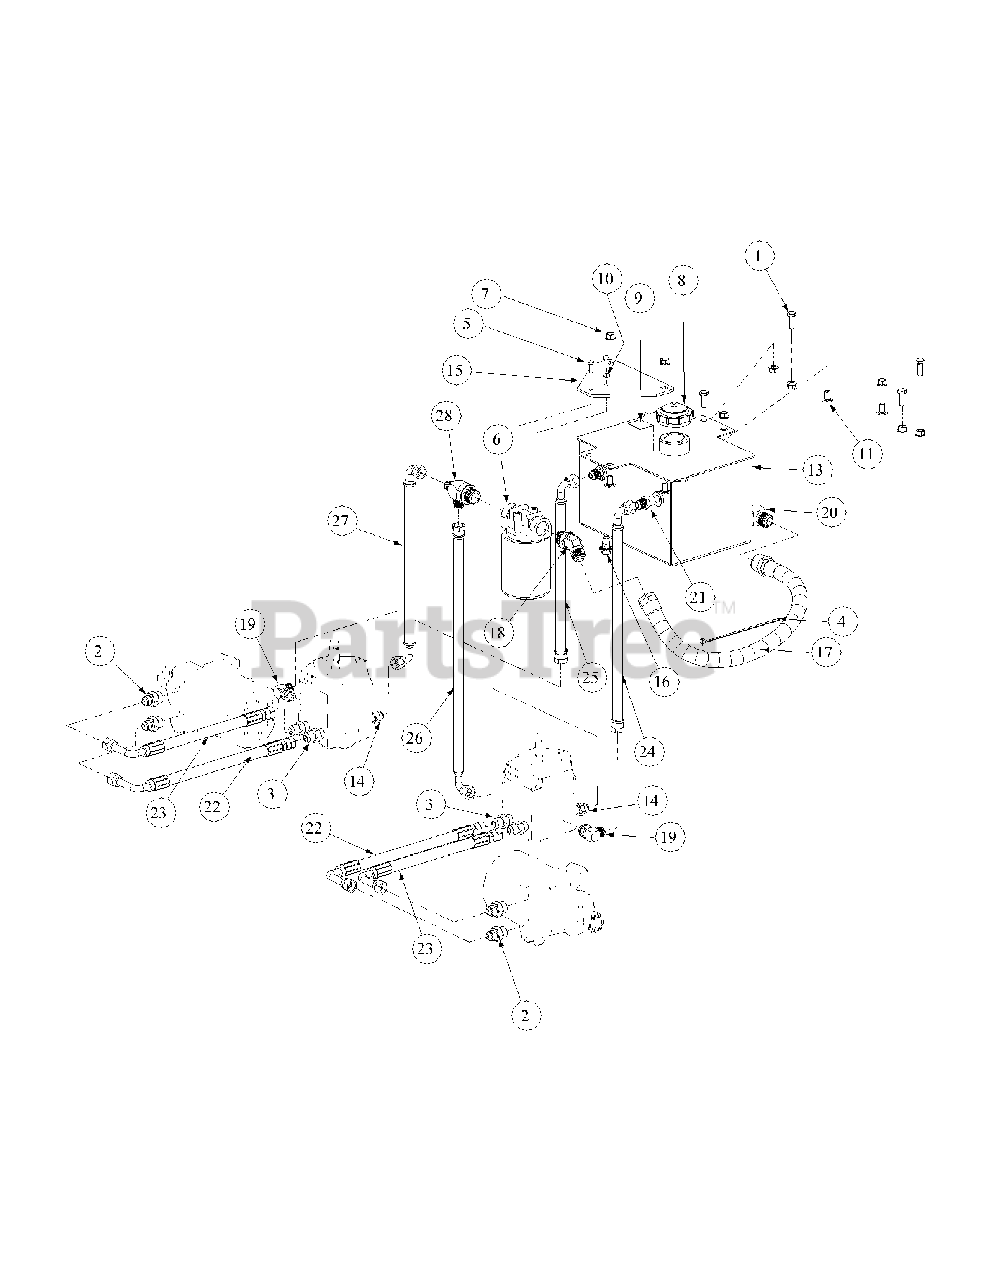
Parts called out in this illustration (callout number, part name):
1	Hex Cap Screw, 3/8-16, 1
2	Fitting 1/2 x 3/4 - O Ring
3	Fitting 1/2 x 3/4 - O Ring to Flare
4	Cable Tie, 3/16 x .05 x 7.4
5	Hex Cap Screw, 1/4-20, .75
6	Filter Head 3/4
7	Hex Nut Flange Lock, 3/8-16
8	Cap, Hydro Oil Tank
9	Decal Oil Only 20W50
10	Lock Washer, 1/4
11	Carriage Bolt, 3/8-16 x .75 LG.
13	Hydraulic Tank Assembly
14	Fitting Connector, 1/2 x 3/8
15	Oil Filter Mounting Plate
16	Oil Pan Drain w/ Seal and Plug
17	Tank to Filter Hose Assembly
18	Connector, 3/4 x3/4
19	Elbow Fitting, 3/8 O-ring, 1/2 Flare
20	Fitting Elbow, 1/2 x 1/2
21	Fitting, 3/8 NPT, 1/2 Flare
22	Long Pressure Hose Assembly
23	Short Pressure Hose Assembly
24	17.75" Return Hose Assembly, RH
25	14" Return Hose Assembly, LH
26	21.25" Supply Hose Assembly, RH
27	15.50" Supply Hose Assembly, LH
28	Tee Fitting, 3/4 x 1/2 x 1/2
